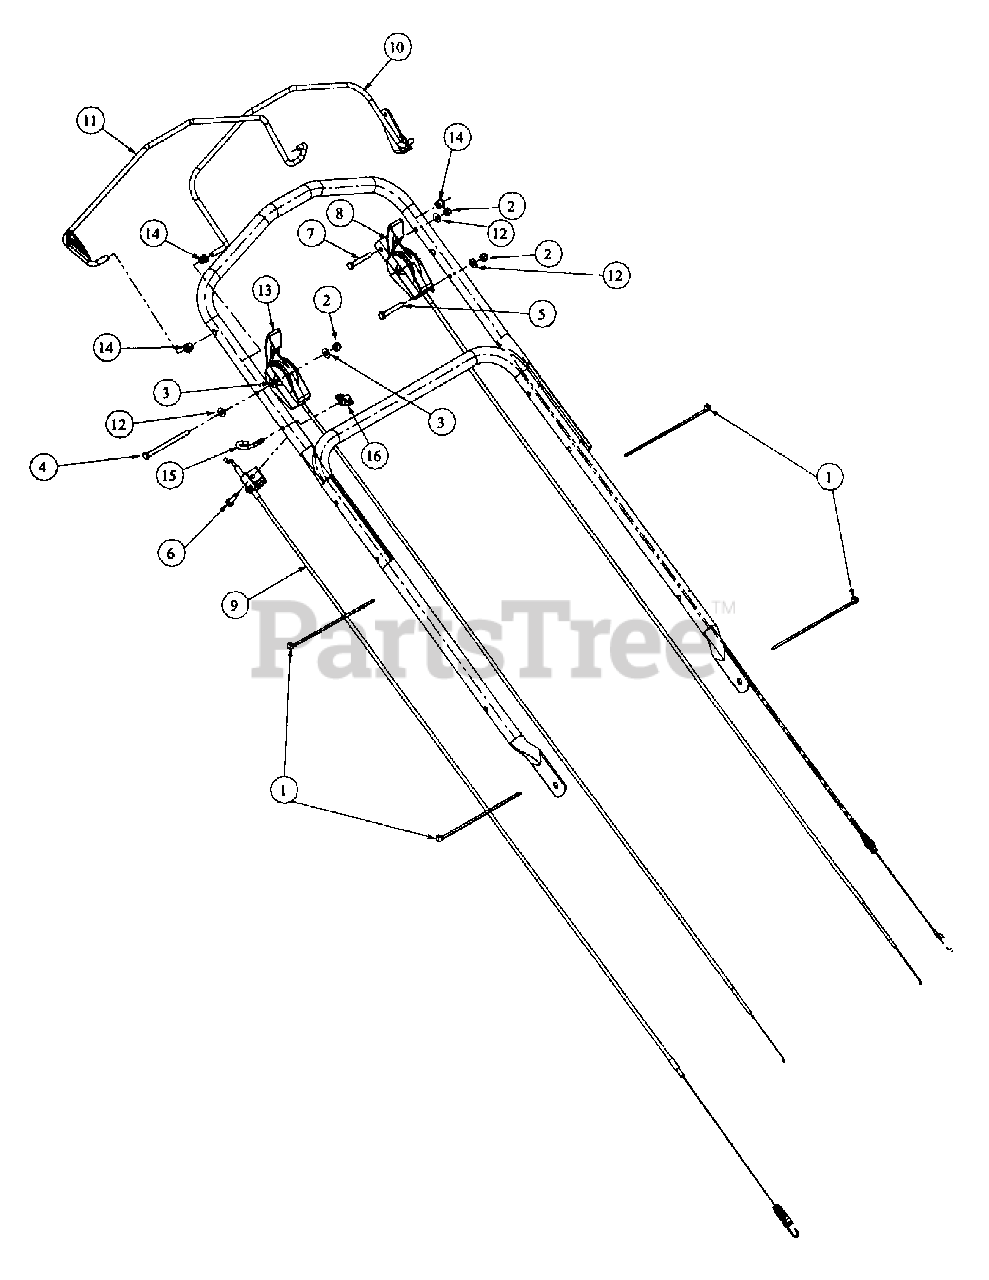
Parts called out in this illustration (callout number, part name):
1	Cable Tie, 3/16 X .05 X 7.4
2	Hex Nut, Lock, 1/4-20
3	Flat Washer 1/4 x .630 x .0515
4	HHCS, 1/4-20, 2.25
5	Hex Head Cap Screw 1/4-20
6	Screw TT 1/4-20, 1.000
7	HHCS, 1/4-20, 2.50
8	Control, BBC, W/Cable
9	Cable, Clutch Speed Adjuster
10	Lever, Control Bail, W/BBC
11	Bail, Clutch, Transmission
12	Saddle Washer, 320 ID x .93 OD
13	Control Throttle, KW
14	Snap Bushing, .3125 Dia.
15	Eye Bolt, 1/4-20, Bent Rope Guide
16	Handle Knob, ERS 1/4-20
